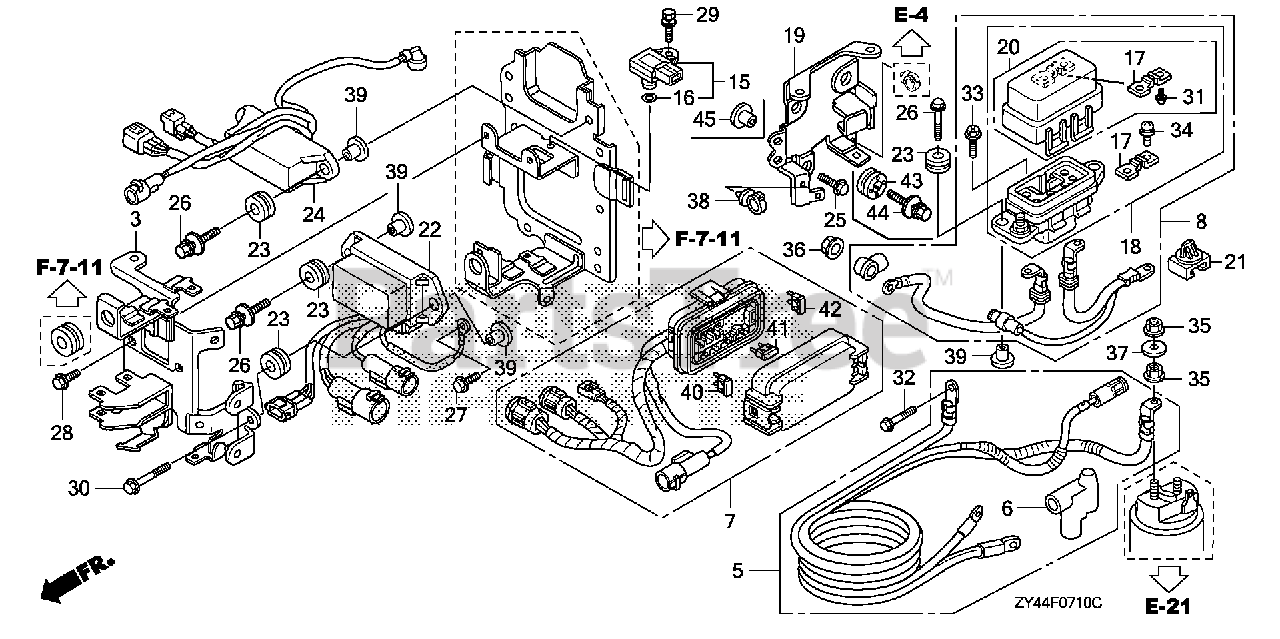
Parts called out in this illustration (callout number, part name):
3	BRACKET, CONNECTOR A
5	CABLE ASSY., STARTER
6	COVER, STARTER TERMINAL
7	CABLE ASSY., MAIN FUSE
8	CABLE ASSY., ALTERNATOR FUSE
15	SENSOR ASSY., MAP
17	FUSE (150A)
18	BOX ASSY., FUSE (150A)
19	BRACKET, FUSE BOX
20	COVER ASSY., FUSE (150A)
21	CLIP, CONNECTOR HOLDER (B)
22	RELAY ASSY., POWER TILT
23	GROMMET, RELAY
24	RELAY ASSY., MAIN
25	BOLT, FLANGE (6X14) (CT200)
26	BOLT-WASHER (6X25)
27	BOLT, FLANGE (6X12)
28	BOLT, FLANGE (6X10)
29	BOLT-WASHER (5X18)
30	BOLT, FLANGE (6X22)
31	SCREW-WASHER (3X7)
32	BOLT, FLANGE (8X18)
33	BOLT-WASHER (6X16)
34	SCREW-WASHER (5X12)
35	NUT-WASHER (8MM)
36	NUT-WASHER (6MM)
37	WASHER, PLAIN (8MM)
38	CLIP, HARNESS
39	COLLAR, MODULE IGNITION CONTROL CASE (CDI)
40	FUSE, MINI (10A)
41	FUSE, MINI (15A)
42	FUSE, MINI (30A)
43	GROMMET, RELAY BRACKET
44	BOLT-WASHER (6X27) (CT200)
45	COLLAR, MODULE IGNITION CONTROL CASE (CDI)
